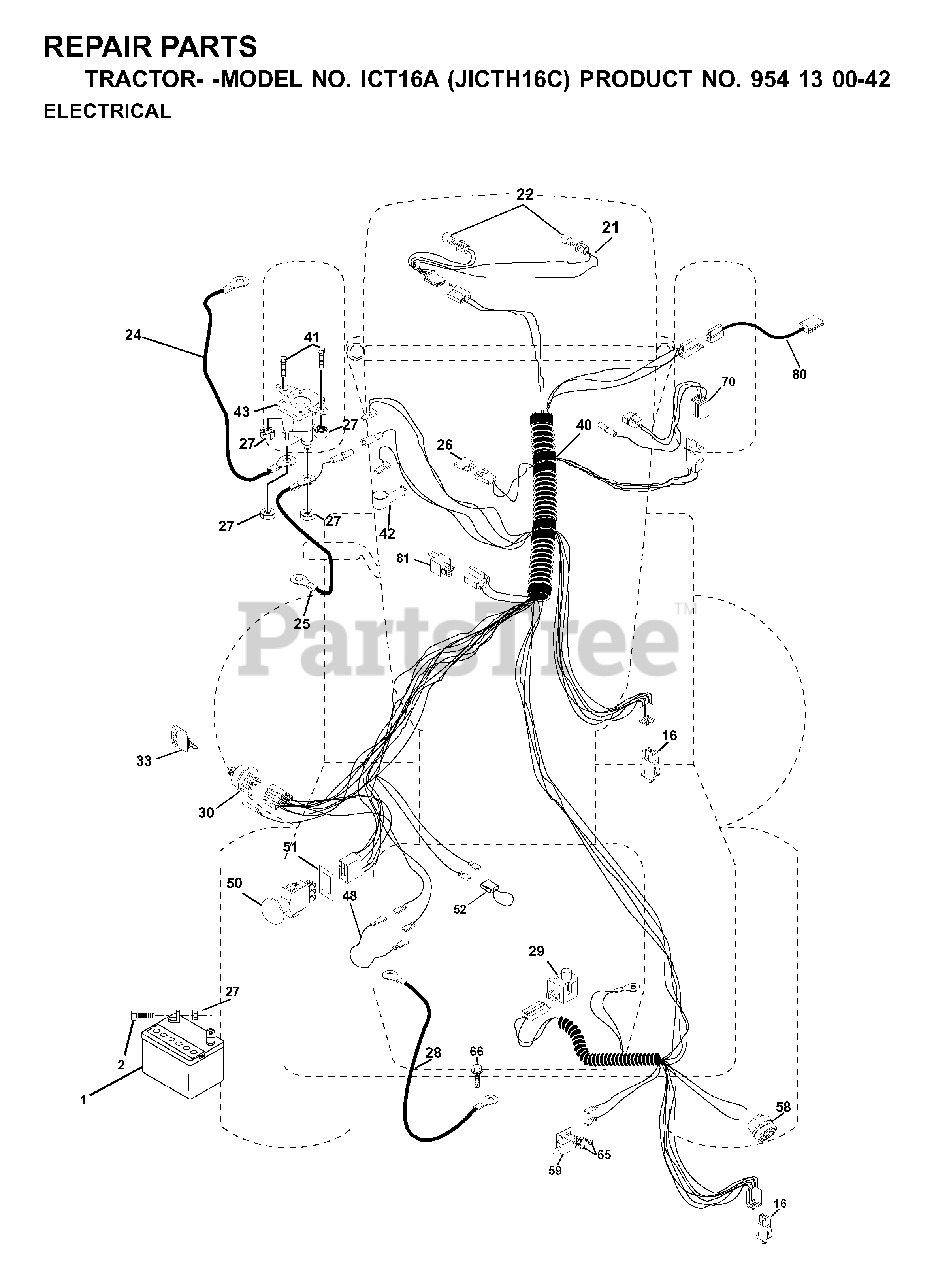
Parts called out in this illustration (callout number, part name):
1	BATTERY 12 VOLT 25 AMP
16	SWITCH INTERLOCK
20	NUT
21	HARNESS ASM, LIGHT W/4152J
22	LIGHTBULB
24	BATTERY CABLE GT
25	CABLE BATTERY
26	FUSE 15 AMP
27	NUT
28	CABLE GROUND
29	PLUNGER SWITCH (COLOR:OLIVE)
33	KEY MLD GEN DELTA
40	HARNESS IGN
42	TERMINAL COVER
43	SOLINOID
50	PTO SWITCH
51	RETAINING RING
52	WIRE PROTECTION LOOP
58	BUZZER
80	HARNESS, CLUTCH
81	RELAY.ASSY.T
